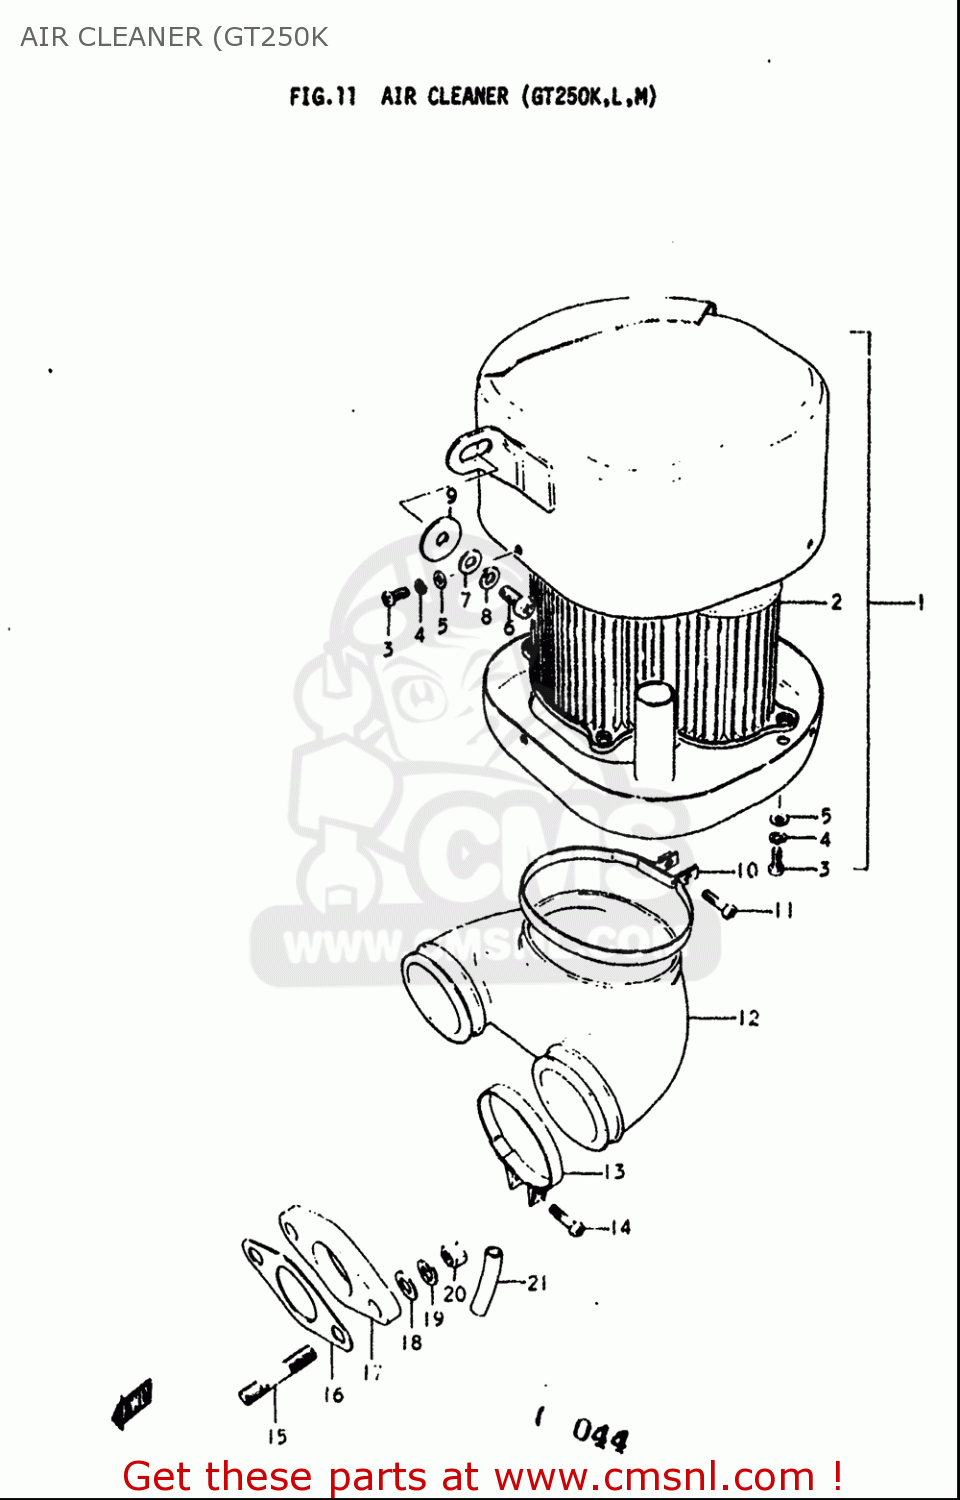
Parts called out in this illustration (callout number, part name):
2	FILTER ASSY
3	SCREW
4	WASHER,LOCK
5	WASHER
6	SCREW
7	WASHER
8	WASHER,LOCK
9	WASHER
10	CLAMP
11	SCREW
12	HOSE,CARBURETOR AIR INLET
13	CLAMP
14	SCREW
15	STUD BOLT
16	GASKET,CARBURETOR (NAS)
18	WASHER
19	WASHER,LOCK
20	NUT
21	HOSE(6X10X600)
